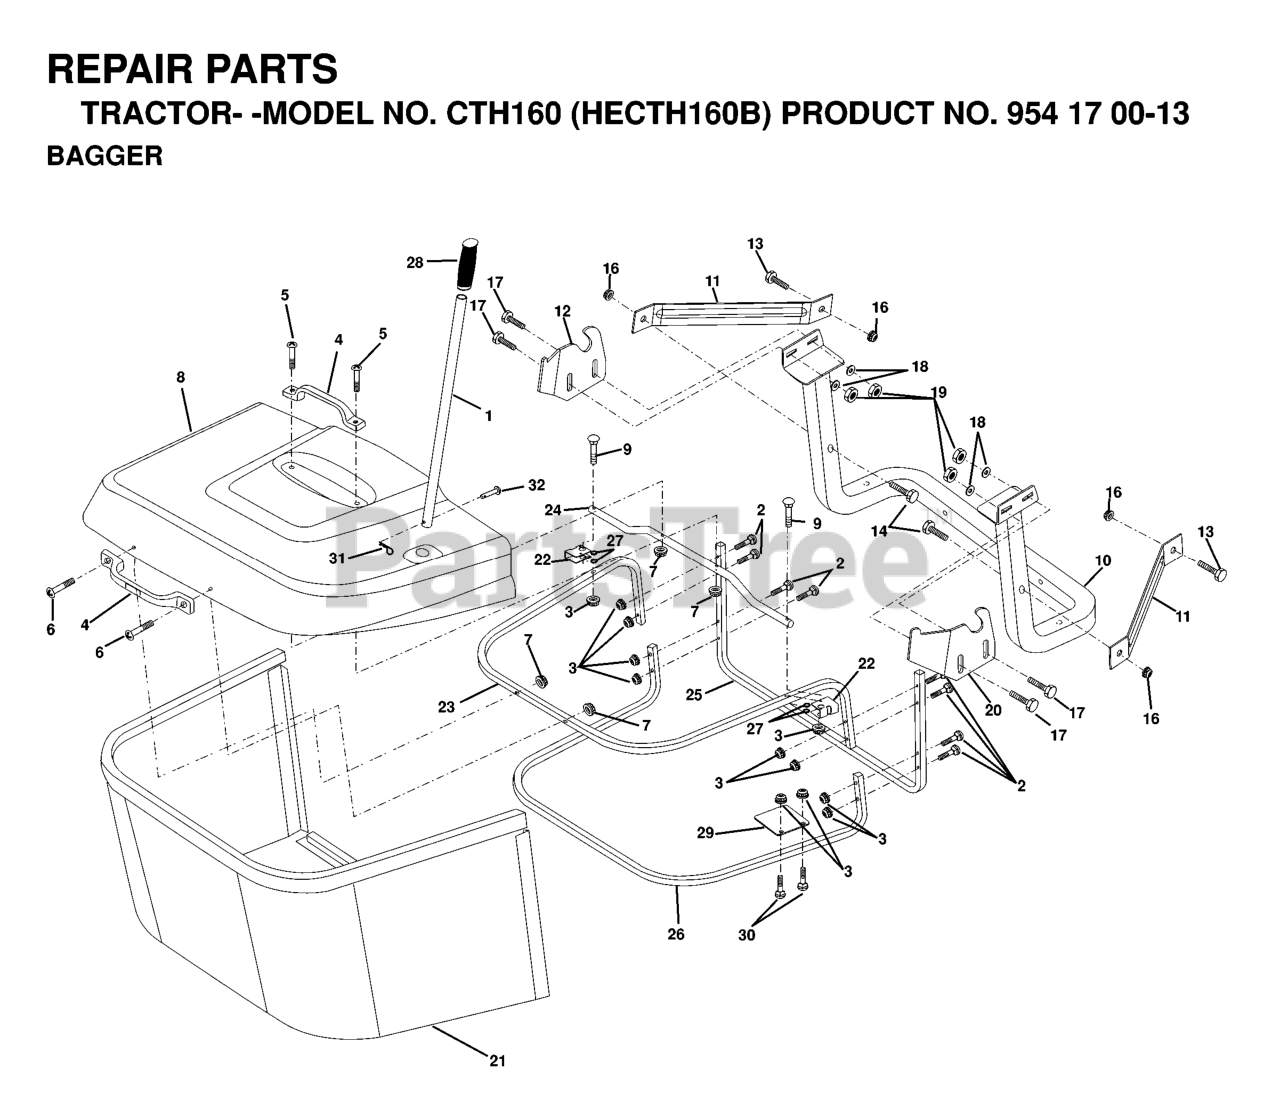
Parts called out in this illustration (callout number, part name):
1	TUBE HANDLE
2	Bolt Carriage 1/4-20 x 2.0 Gr.5
3	NUT T
5	SCREW.PAN.HEAD
6	REPL BY 532 75 00-29
8	COVER
9	Bolt Carriage 1/4-20 x 2.25d x Gr.5
11	BRACKET.SUPPORT.UPPER.BAG.CRD
14	Bolt Hex 3/8-16 x 2-1/2 Gr. 5
16	NUT LOCK FLG 3/8-16 UNC
17	RP BOLT 5/16-18 X3/4 ZN/YEL GR
18	Washer 11/32 x 1-1/4 x 16 Ga.
19	NUT.71038.31-18.HEX.NYLOCK
21	BAG
22	BRKT.SIDE.BAG.CRD
23	TUBE.UPPER.BAG.CRD
24	TUBE.PIVOT.BAG.CRD.BLACK
26	TUBE.LOWER.BAG.CRD
28	GRIP.HANDLE.BLACK
30	Bolt Carriage 1/4-20 x 1 Gr.5
31	RETAINER M
32	RIVET,DRILLED
